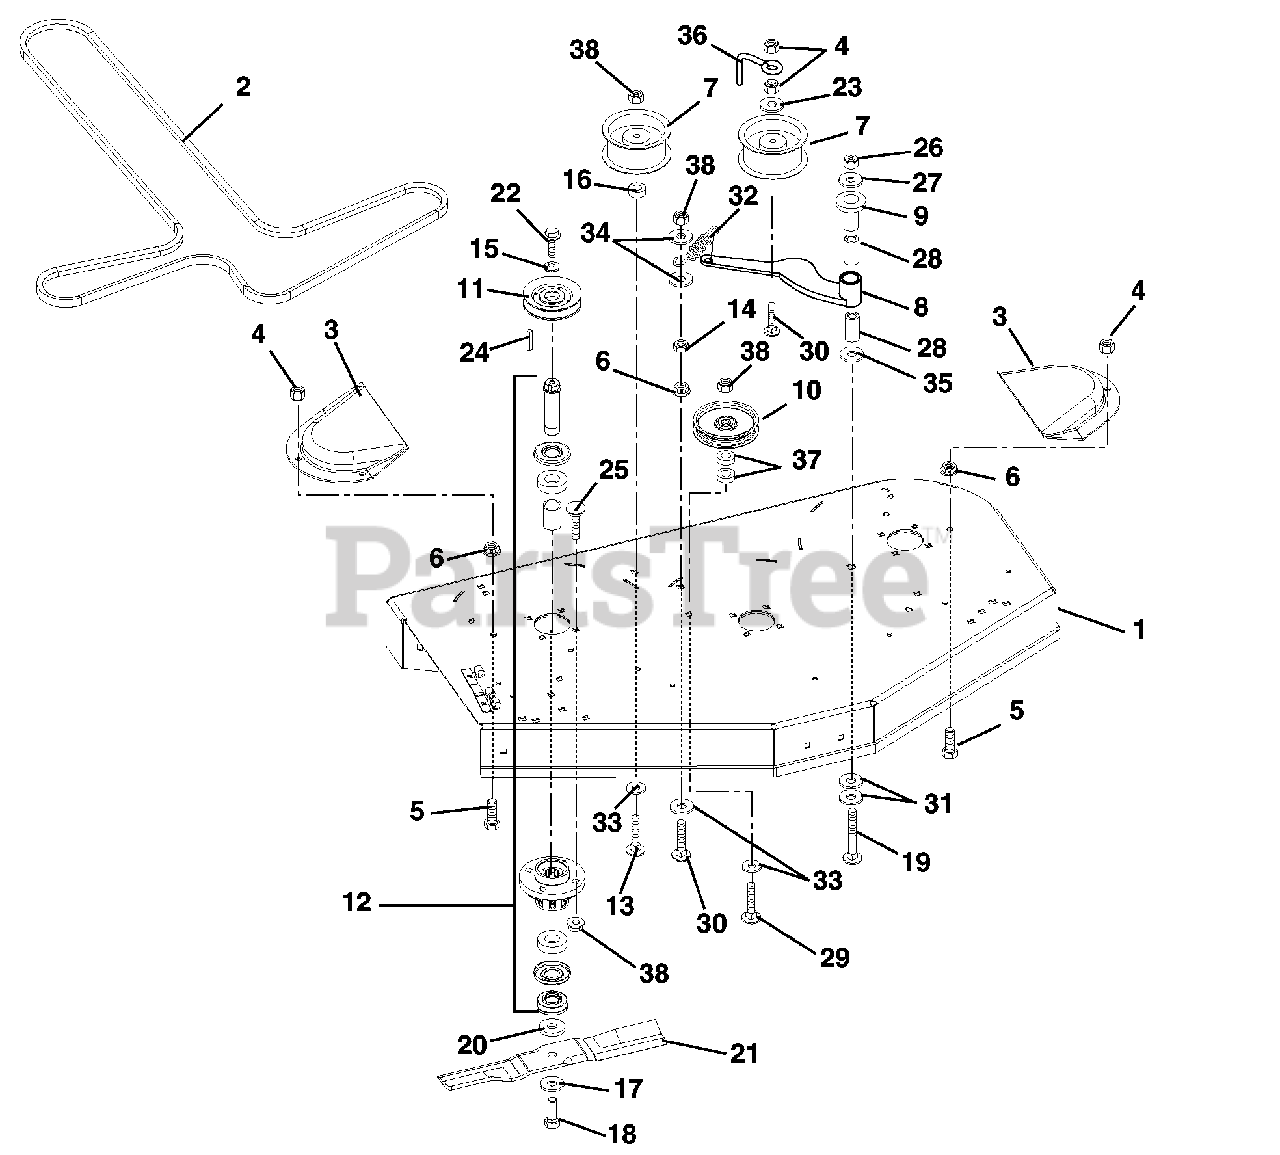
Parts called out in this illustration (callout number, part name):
1	40" MOWER DK W/DECALS C-L2078
1	40" MOWER DECK ASSY COMPLETE
1	44" MOWER DK W/DECALS C-L2078
1	44" MOWER DECK ASSY COMPLETE
1	44" MOWER DECK CMPLT (GLOBAL)
1	48" MOWER DK W/DECALS C-L2078
1	48" MOWER DECK ASSY COMPLETE
1	52" MOWER DK W/DECALS C-L2078
1	52" MOWER DECK ASSY COMPLETE
1	52" MOWER DECK ASSY COMPLT CE
2	V-BELT, HA-WRAPPED
2	BELT,HA WRAPPED
4	NUT-LK-TOP-FLG .38-16 BLKZC
5	BLT-HEX .38-16X1.00 GR5 BKZC
6	NUT-SPNLK-FLG .375-16 BKZC
7	IDLER FLANGED 3.50
8	WELDMENT, IDLER ARM
9	BEARING, PEDESTAL
10	IDLER-FLAT 4.00 X .38 NWHAMSHR
11	SHEAVE, SPINDLE - 4.00 DIA.
11	SHEAVE, SPINDLE - 4.75 DIA.
11	SHEAVE, SPINDLE - 4.25 DIA.
11	SHEAVE, SPINDLE - 4.50 DIA.
12	ASSEMBLY, SPINDLE
13	BLT-RDHDSQNK .38-16X2.25 G5BZ
14	@NUT-LK-CTR-JAM .375-16 YWZC
15	WASHER, CUPPED SERRATED, .375
16	SPACER, .39 X 1.50 X .380
17	WSHR-BLVL .669X1.535X.138
18	BLT-HEX .62-18X1.75 GR8 YWZC
19	@BLT-RDHDSQNK .50-13X3.75 G5YZ
20	WSHR-FLT .640X1.75X.250 YWZC
21	MOWER BLADE, 13.94"
21	BLADE, 15.50"
21	BLADE, MOWER (16.19")
21	BLADE, MOWER (18.00")
21	BLADE, 36" SAND, TUNGSTEN
21	BLADE, 15.5 CE (44" ZOOM)
22	BLT-HEX .38-16X1.00 YZ GR8
23	WSHR-FL-STL .406X1.00X.188 YWZ
24	KEY, SQ .25 X .38 X .25
25	@BLT-RDHDSQNK .38-16X1.25 BKZC
26	@NUT-LK-TOP-FLG .50-13 YWZC
27	WSHR-FL-STL .531X1.250X.10 YWZ
28	BRG, 1.00 X 1.12 X .75
29	@BLT-RDHDSQNK .38-16X1.75 G5YZ
30	@BLT-RDHDSQNK .38-16X2.75 G5YZ
31	WSHR-FL-STL.755X1.375X.062YWZC
32	SPRING, EXTENSION
33	@WSHR-FL-STL.563X1.38X.109YWZC
34	WSHR-FL-STL .375X1.125X.065YWZ
35	WSHR-FL-STL .515X1.625X.250 YZ
36	FINGER - BELT
37	WSHR-FL-STL .380X1.50X.125YWZC
38	NUT-3/8-16 FLG NYLOC BK ZN
